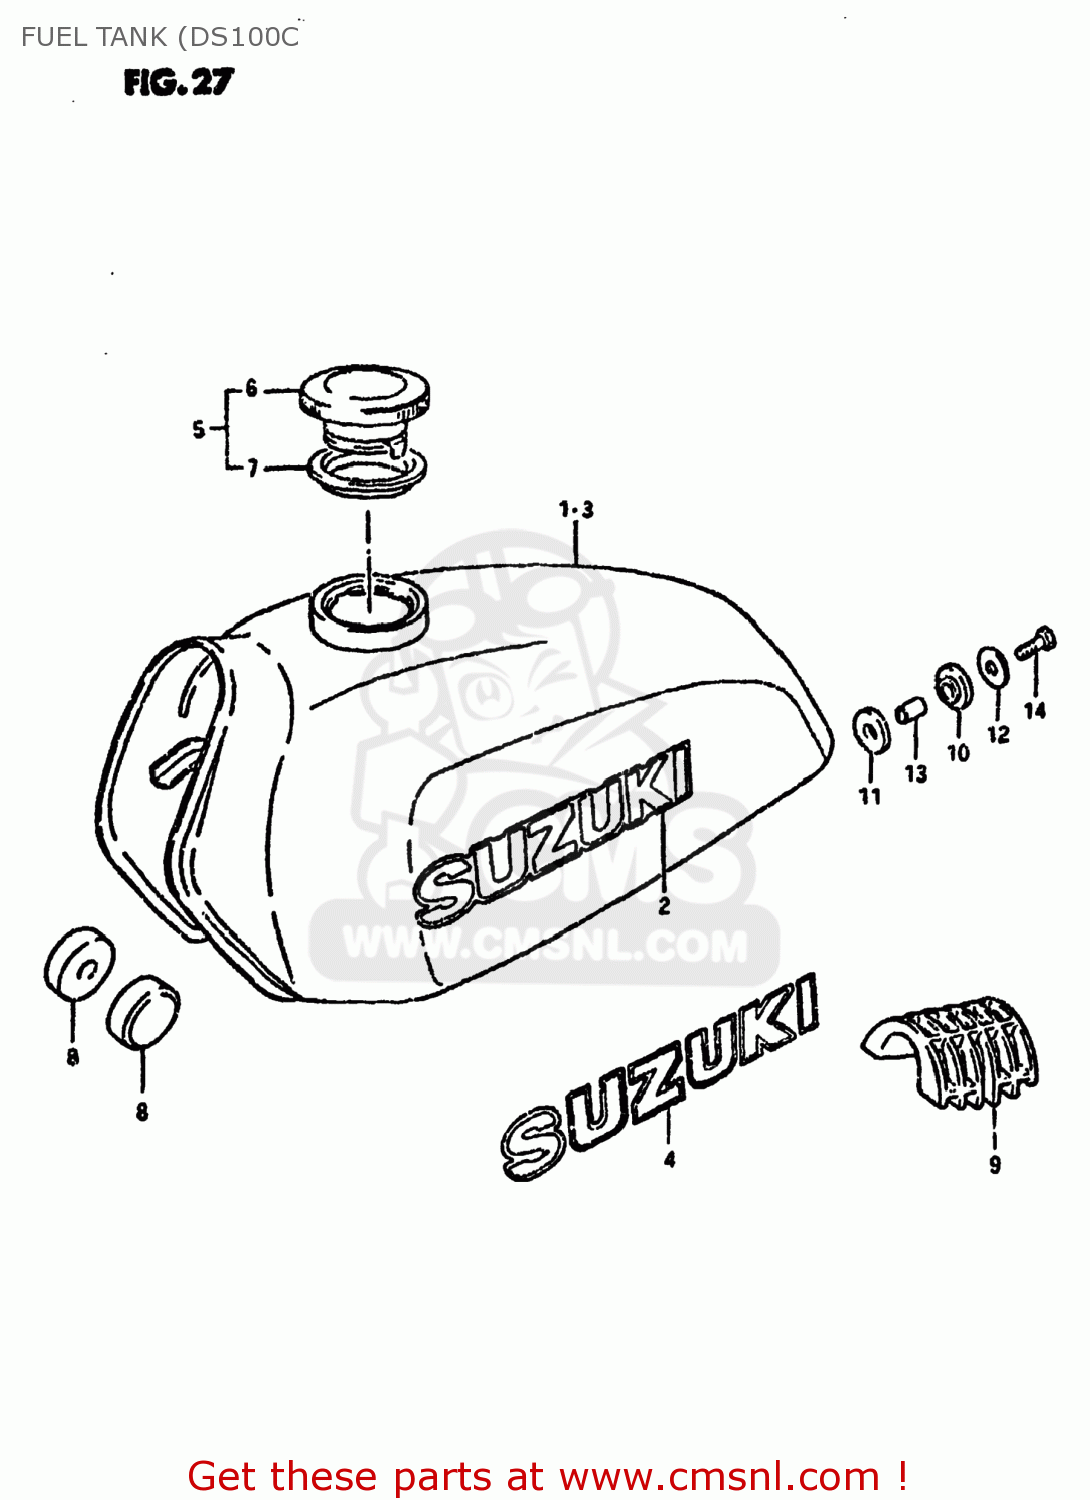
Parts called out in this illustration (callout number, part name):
1	TANK ASSEMBLY,FUEL
2	EMBLEM
3	TANK ASSEMBLY,FUEL
4	EMBLEM
5	CAP ASSY,FUEL TANK FILLER
6	CAP,FUEL TANK
7	GASKET (NAS)
8	CUSHION
9	CUSHION
10	CUSHION
11	CUSHION
12	WASHER (8.5X29X1.6)
13	SPACER (8.2X12X17)
14	BOLT (8X30)
